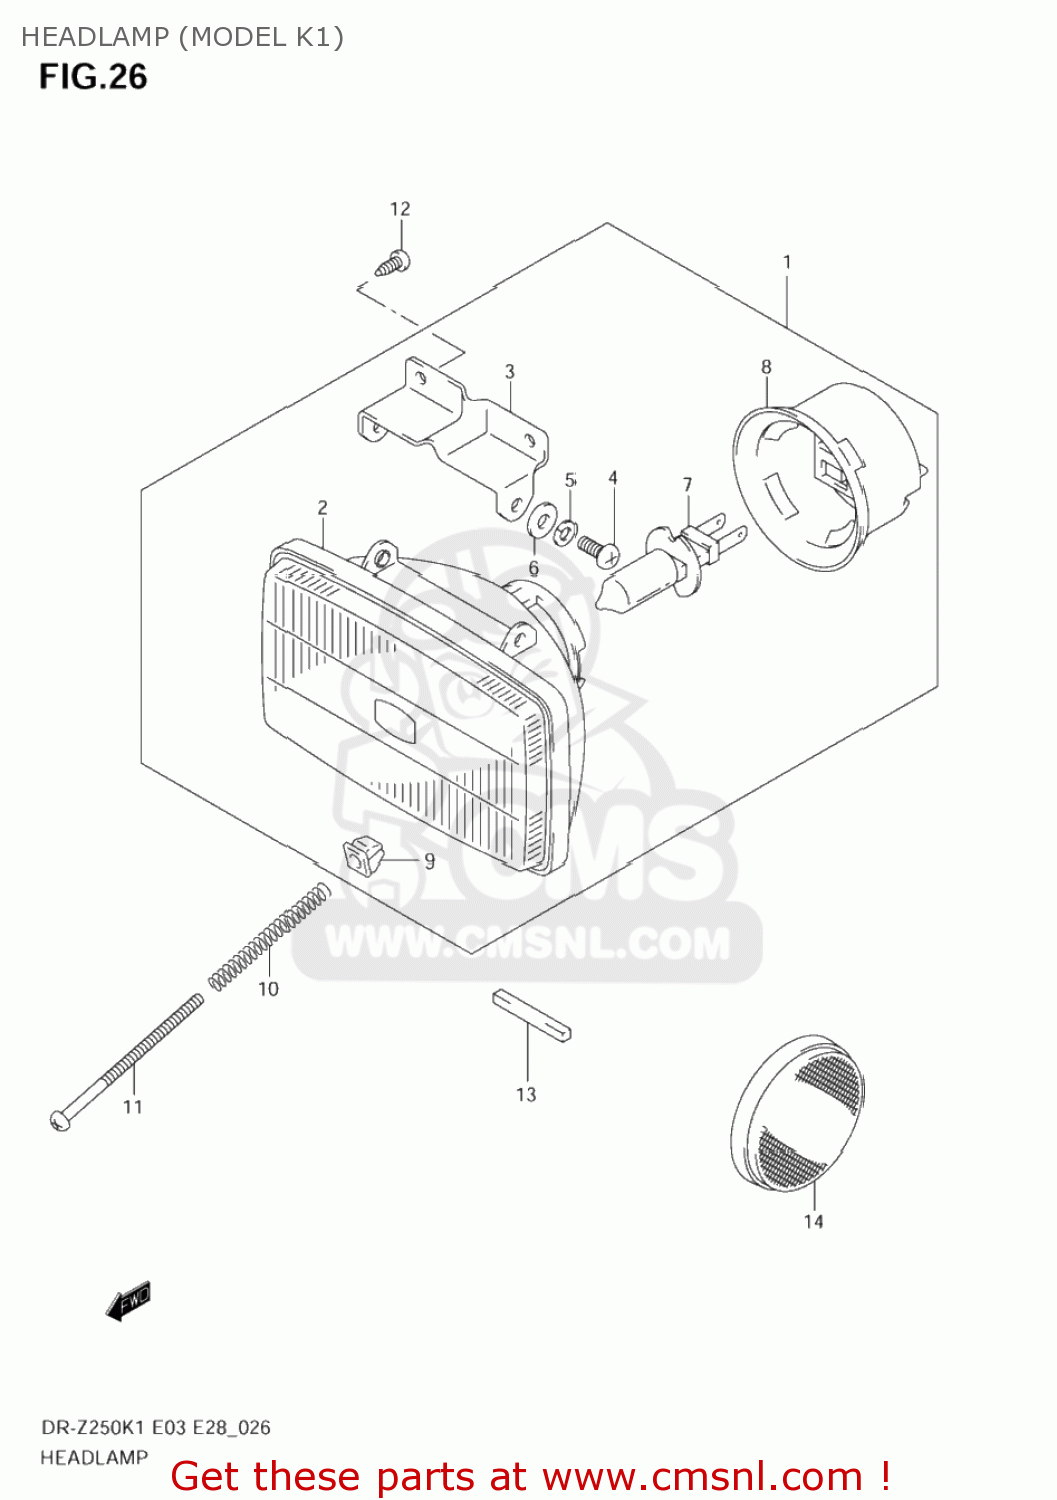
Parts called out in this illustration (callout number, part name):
1	HEADLAMP ASSY
2	HEADLAMP ASSY
3	BRACKET,LAMP
4	SCREW
5	WASHER,LOCK
6	WASHER
7	BULB(12V55W)
8	COVER,SOCKET
9	NUT,ADJUSTING
10	SPRING,HEAD LAMP ADJUSTER
11	SCREW(4X45)
12	SCREW
13	PROTECTOR(50X50X5)
14	REFLECTOR,REFLEX FR
